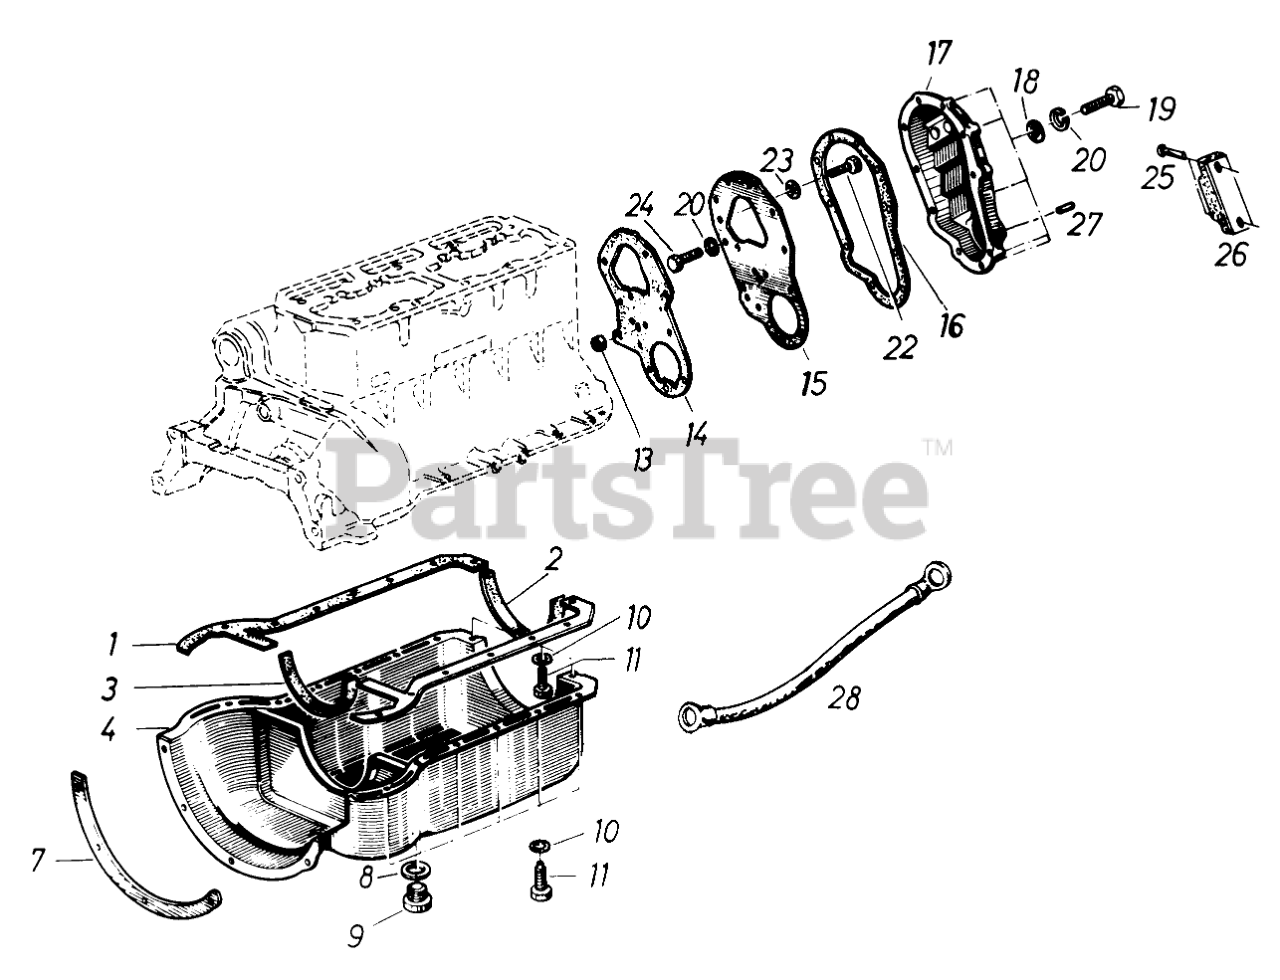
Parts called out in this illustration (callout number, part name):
1	Gasket
2	Gasket
3	Gasket
4	Oil Sump
7	Reinforcement
8	Gasket
10	Lock Washer
11	Screw
14	Gasket
15	Timing Chain Cover Plate
16	GASKET
17	Distributor Cap
18	Washer
19	Screw
20	Lockwasher
22	Screw
23	Lock Washer
24	Screw
25	Rivet
26	Chain Guide
28	Ground Cable Chassis-Engine
